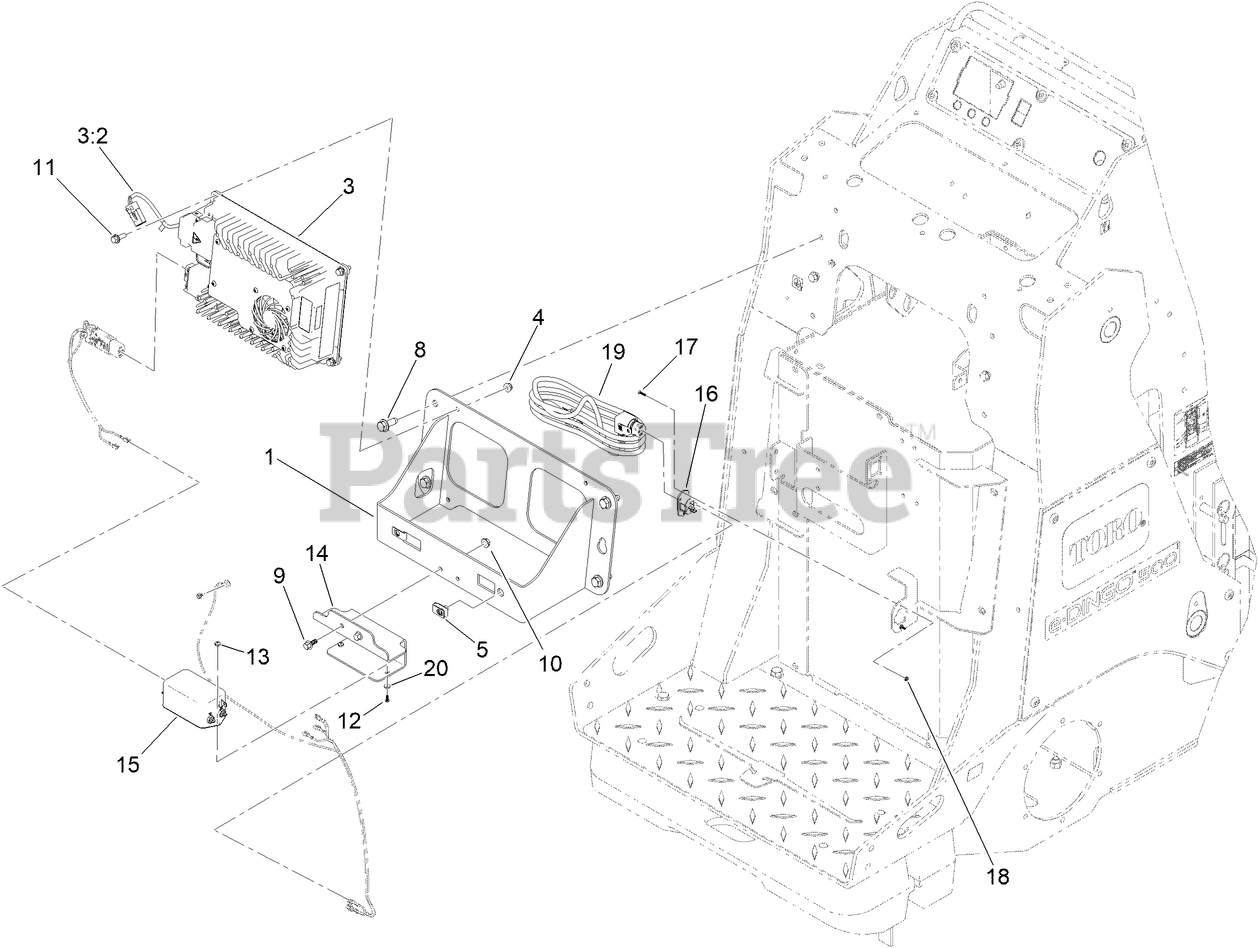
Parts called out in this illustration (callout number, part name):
1	MOUNT-CHARGER [BLACK]
3	CHARGER-ONBOARD
3:2	KIT-SERVICE, DC HARNESS
4	NUT-HF
5	NUT-CLIP, U
8	SCREW-HWH
9	SCREW-HHF
10	NUT-HF
11	SCREW-HHF
12	SCR,MCH,6-32X3/8,PHPH,SST,ROHS
13	NUT-LOCK
14	BRACKET - FILTER
15	FILTER
16	CONNECTOR-IEC
17	Ball, Governor
18	NUT-LOCK, NI
19	CORD-AC, 120V
20	WASHER-FLAT
